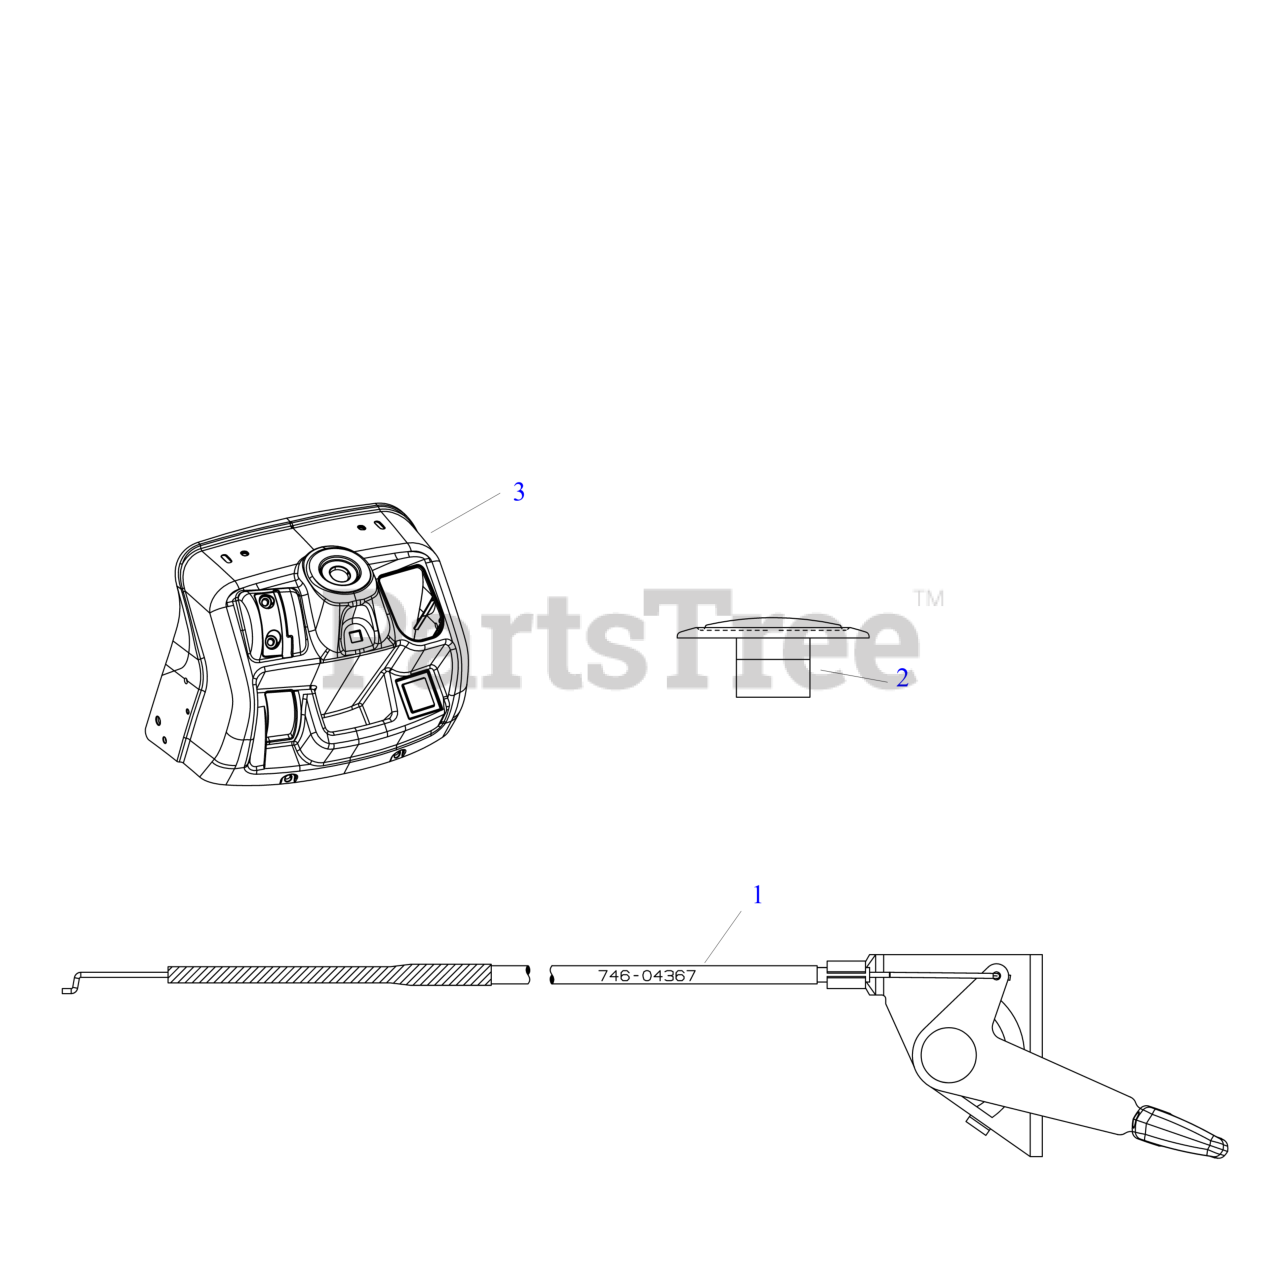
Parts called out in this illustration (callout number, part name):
1	THROTTLE CABLE 28" x 1.1
2	CHOKE PLUG
3	UPPER DASH
